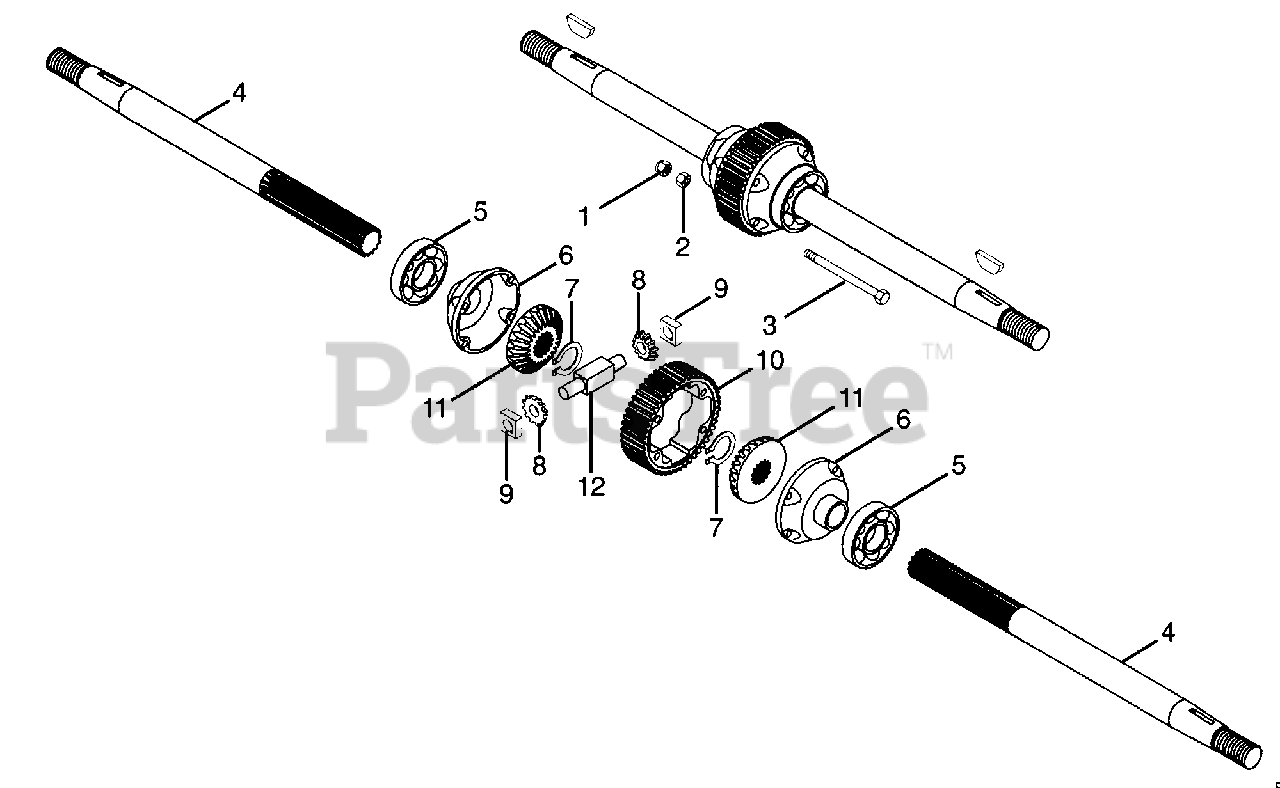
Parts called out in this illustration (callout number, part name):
1	Nut-Locking-Center .312-18 Grade 5
2	Nut-Hex .312-18 Grade 8
3	Bolt-Hex .31-18 x 2.75 Grade 8
4	Axle-Bevel Gear Differential
5	Bearing-Ball 1.57 x 2.68 x .59
6	Cap-Differential End
7	Ring-Retaining-External 1.150 x .093
8	Pin-Bevel
9	Block-Drive
10	Gear-Final Drive
11	Gear-Bevel
12	Pin-Spider Pinion
